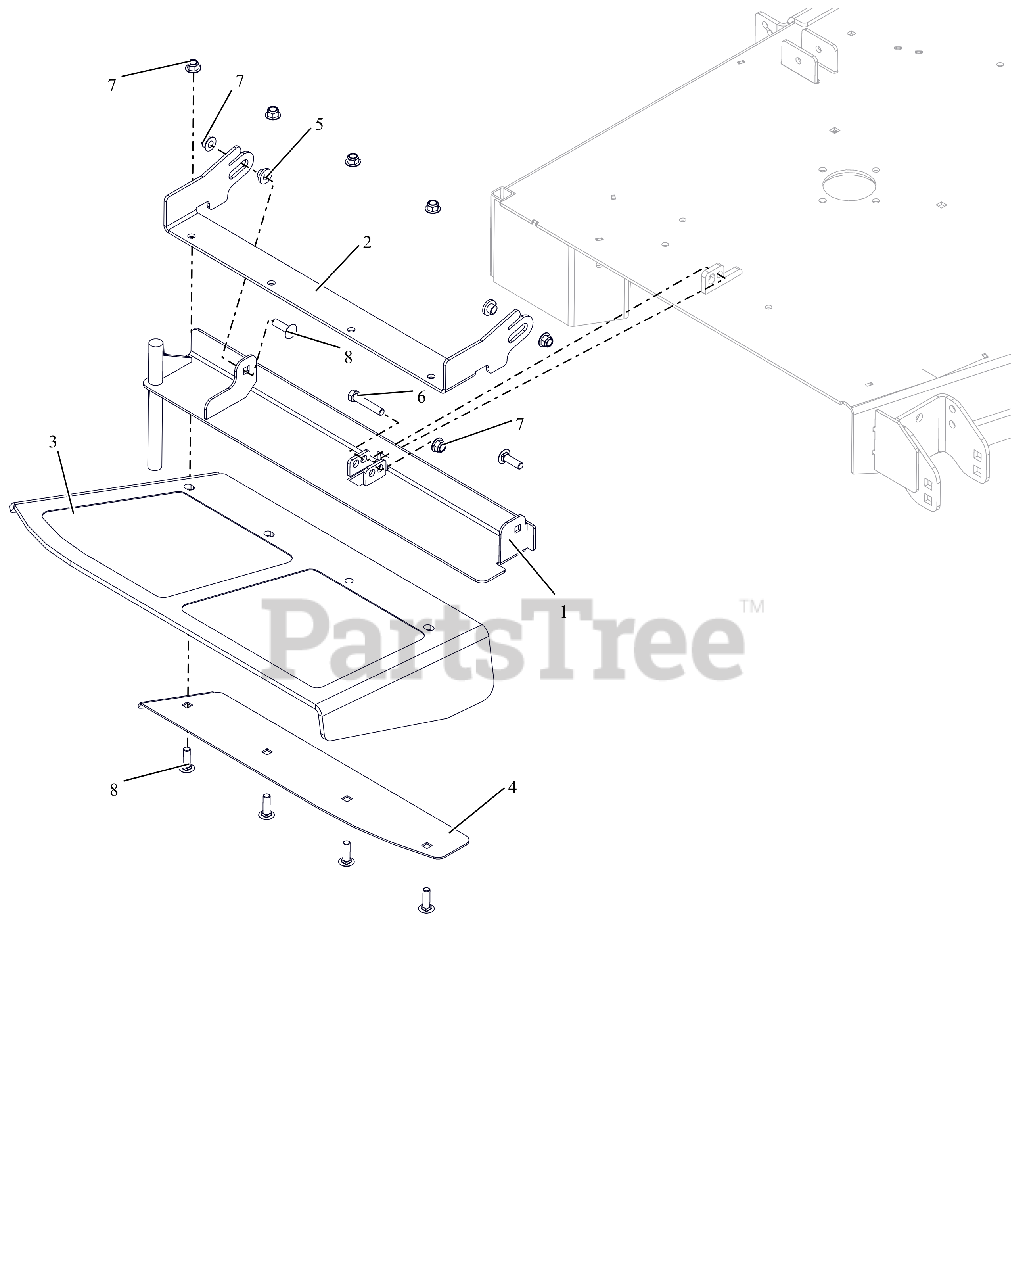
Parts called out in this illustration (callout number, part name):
1	72"DISCH CHUTE MTG WMT W/SAFE
2	72" CHUTE MTG BRKT - RED
3	CHUTE, 72" FORMED RUBBER DISCH
4	72" DISCH CHUTE CLAMP PLT -RED
5	BSHG-FLG .385X.500X.875X.406
6	BLT,HEX .38-16X2.00 G5 ZCC
7	NUT,NYL-FLG .38-16 GF ZCC
8	BLT,RHSSN .38-16X1.25 G5 ZCC
